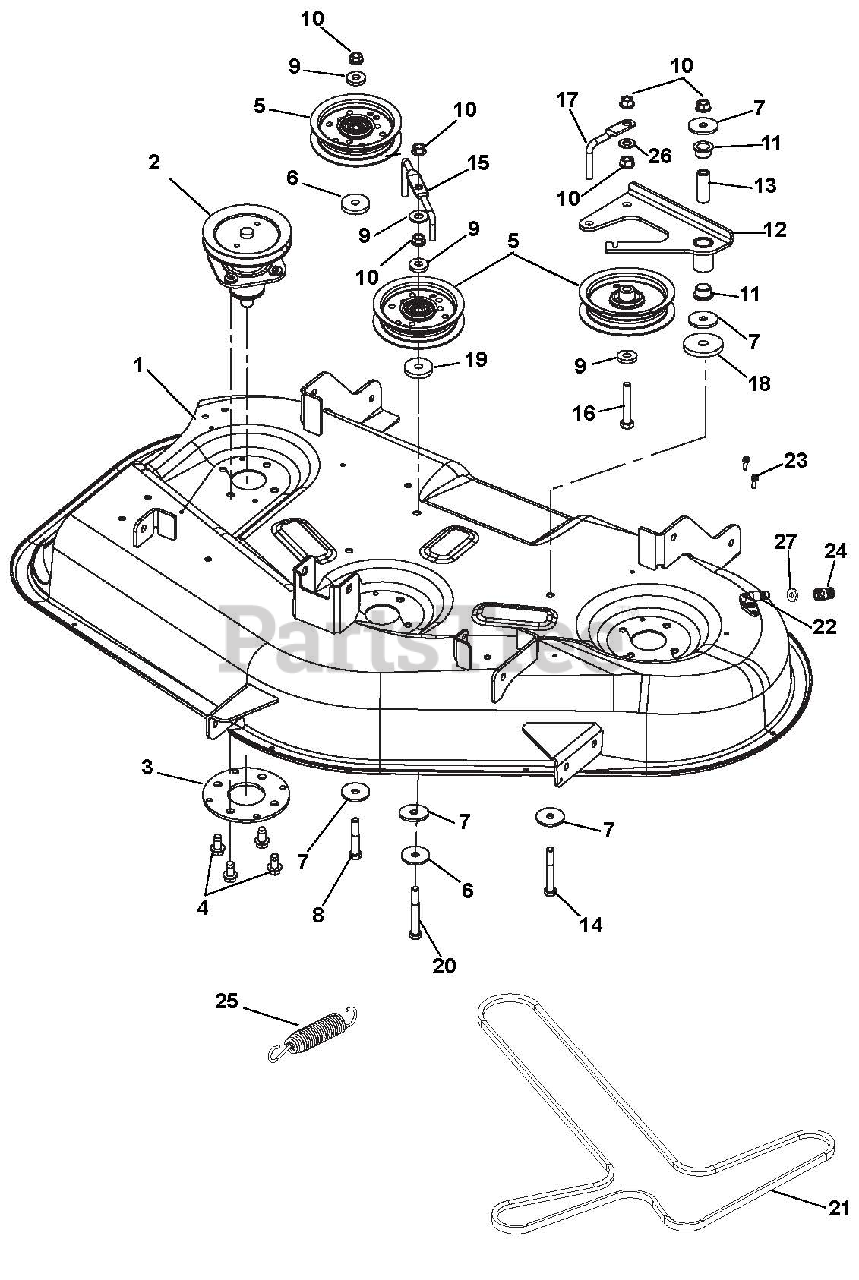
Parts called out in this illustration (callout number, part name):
1	KIT, 42 ARIENS CE DECK W/DECAL
2	KIT, DECK SPINDLE ASM (42)
3	PLATE-REINF, SPINDLE
4	@SCR-TAP .38-16X.75 HWH TR YWZ
5	ASM, IDLER 4"
6	WSHR,FLT STL.406X1.50X.245YWZC
7	WSHR, FLT .380X1.50X.125 ZCC
8	@BLT-HEX .38-16X2.25 GR5 YWZC
9	WSHR-FL-STL .406X1.00X.188 YWZ
10	@NUT-LK-TOP-FLG .38-16 YWZC
11	BSHG-FLG, .625X.750X.500X1.00
12	IDLER ARM
13	SPACER, .375IDX.625ODX1.66 PM
14	@BLT-HEX .38-16X3.00 GR5 YWZC
15	WIREFORM, BELT FINGER
16	@BLT-HEX .38-16X2.25 GR5 YWZC
17	WIREFORM, BELT FINGER
18	WSHR-FL-STL .469X2.00X.25 YWZC
19	@WSHR-FL-STL.438X1.00X.083 YWZ
20	@BLT-HEX .38-16X2.75 GR5 YWZC
21	V-BELT, 4L-WRAPPED
22	ASSY, WASHOUT PORT W/ O-RING
23	@SCR-TAP .25-20X.62 HWH TR YWZ
24	COUPLING, QUICK DISCONNECT
25	SG-TENS .135X.98X6.0 WLD 62
26	@WSHR-FL-STL.406X.812X.065 YWZ
27	O-RING .362X.103X.568
